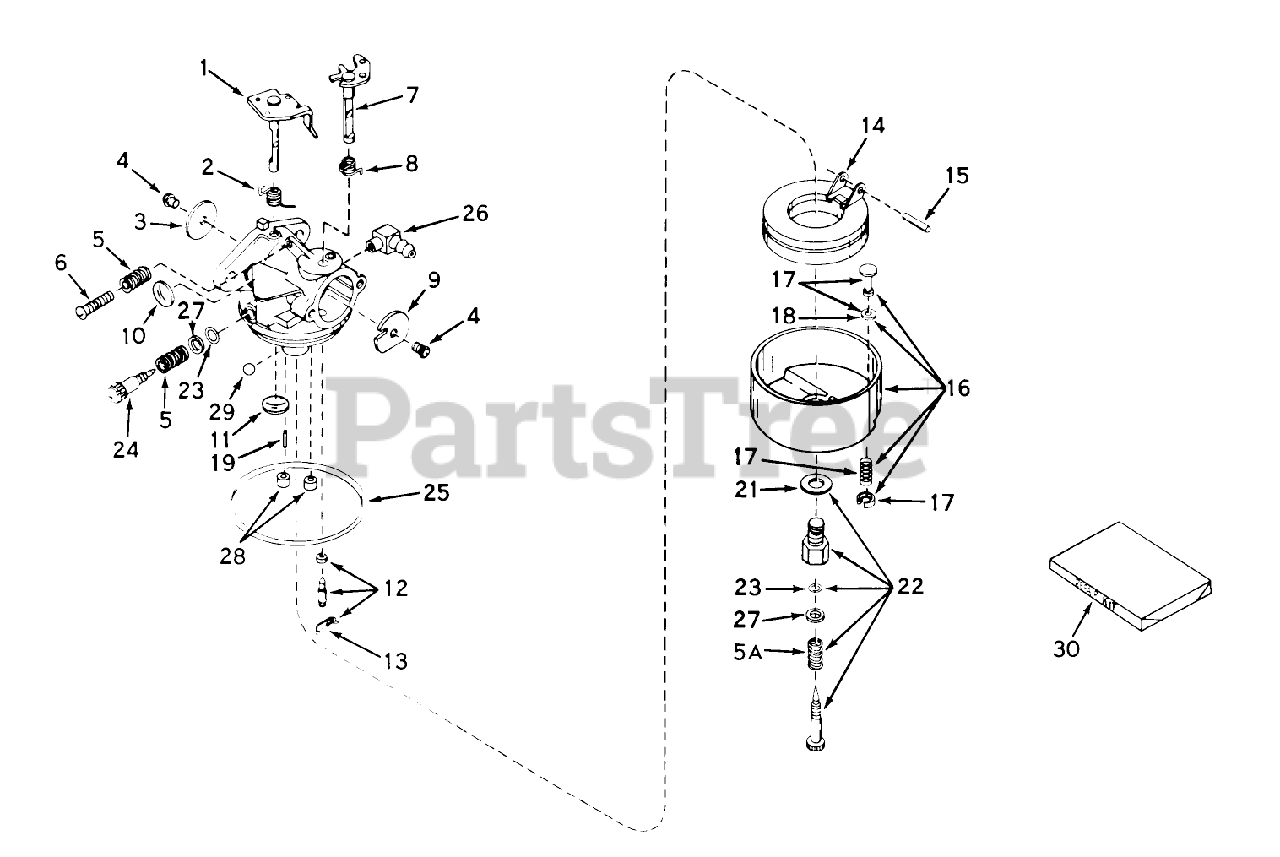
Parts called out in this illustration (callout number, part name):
1	Shaft Lever Assy.
2	Spring, Throtte Return
3	Shutter-Throttle
4	Screw-Shutter
5	Spring-Tension
5A	Spring
6	Screw-Throttle Crack Screw / Idle Speed
7	Shaft Lever Assy., Choke
8	Spring, Choke return
9	Shutter, Choke
10	Plug-Welch, Idle Mixture Well
11	Plug-Welch, Atmospheric Vent
12	Inlet Needle, Seat Clip Assy. (Incl. No. 13)
13	Clip-Spring
14	Float,Carburetor
15	Shaft-Float
16	Bowl Drain Assy., Float (Incl. No. 17)
17	Bowl Drain ASM
18	Gasket-Plunger, Drain
21	Washer-Bowl Nut
22	Adjustment Screw Assembly, Main (Incl. Nos. 5A, 21, 23 27)
23	ORing
24	Screw, Idle Adj.
25	O Ring-Bowl, Float
26	Fitting Fuel Inlet
27	Washer
28	Plug, Cup
29	BalI, Steel
30	Repair Kit
